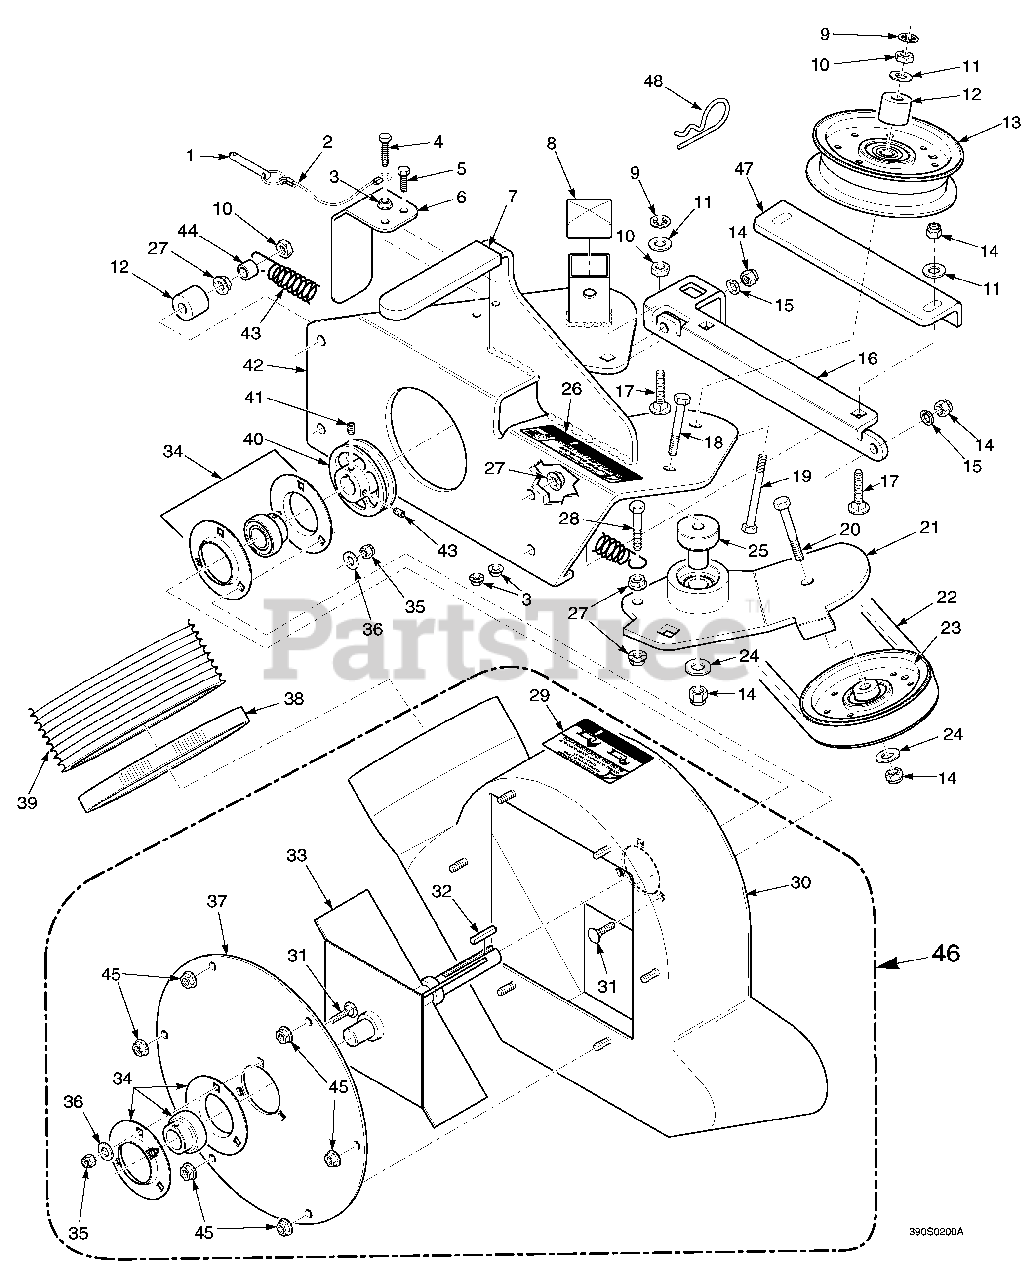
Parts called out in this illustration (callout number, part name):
1	Pin, Ring 2-1/4" Long
2	Lanyard, Deck Height Pin
3	Nut, Serr. Flange 1/4-20
4	Bolt, Hex Head 1/4-20 x 1-1/4"
5	Bolt, Hex Head 1/4-20 x 3/4"
6	Belt Cover, Rear
7	Grip, Blower Lever
8	Cap, Square
9	Nut, Push On 3/8 Thread
10	Lock Nut, 3/8-16
11	Flatwasher, 3/8-.391 x .938 x .105
12	Spacer
13	Pulley, Idler 4" Dia.
14	Nut, Elastic Stop 3/8-16
15	Lockwasher, 3/8-16
16	Plate, Catch Mounting
17	Bolt, Carr. 3/8-16 x 1-1/2"
18	Bolt, Hex Head 3/8-16 x 2-1/4"
19	Bolt, Hex Head 3/8-16 x 3-1/4"
20	Bolt, Hex Head 3/8-16 x 2"
21	Idler Arm Weldment
22	Belt, GC-STC
23	Pulley, 4" O.D.
24	Washer, 3/8 Hardened
25	Pivot, Idler
26	Decal, Belt Cover
27	Nut, Serr. Flange 3/8-16
28	Bolt, Hex Head 3/8-16 x 1-1/2 Gr. 8
29	Decal, Danger
30	Blower Housing Weldment,
31	Bolt, Carr. 5/16-18 x 3/4" Gr. 5
32	Key, 1/4 x 1/4 x 1-1/2"
33	Fan Weldment
34	Bearing with Locking Collar
35	Nut, Elastic Stop 5/16-18
36	Flatwasher, 5/16-.344 x .688 x .065
37	Cover, Blower Housing
38	Clamp, 6-1/2" Max Dia.
39	Hose, 6" Dia.
40	Pulley, 4-3/4" O.D. - 1" Bore
41	Set Screw, 5/16-18 x 3/8"
42	Frame Weldment, Blower Mount
43	Spring, Main Drive
44	Spacer
45	Nut, Serr. Flange 5/16-18
46	Blower Housing Assembly
47	Plate, Blower Catch
48	Hair Pin Cotter, .243 x 4"
